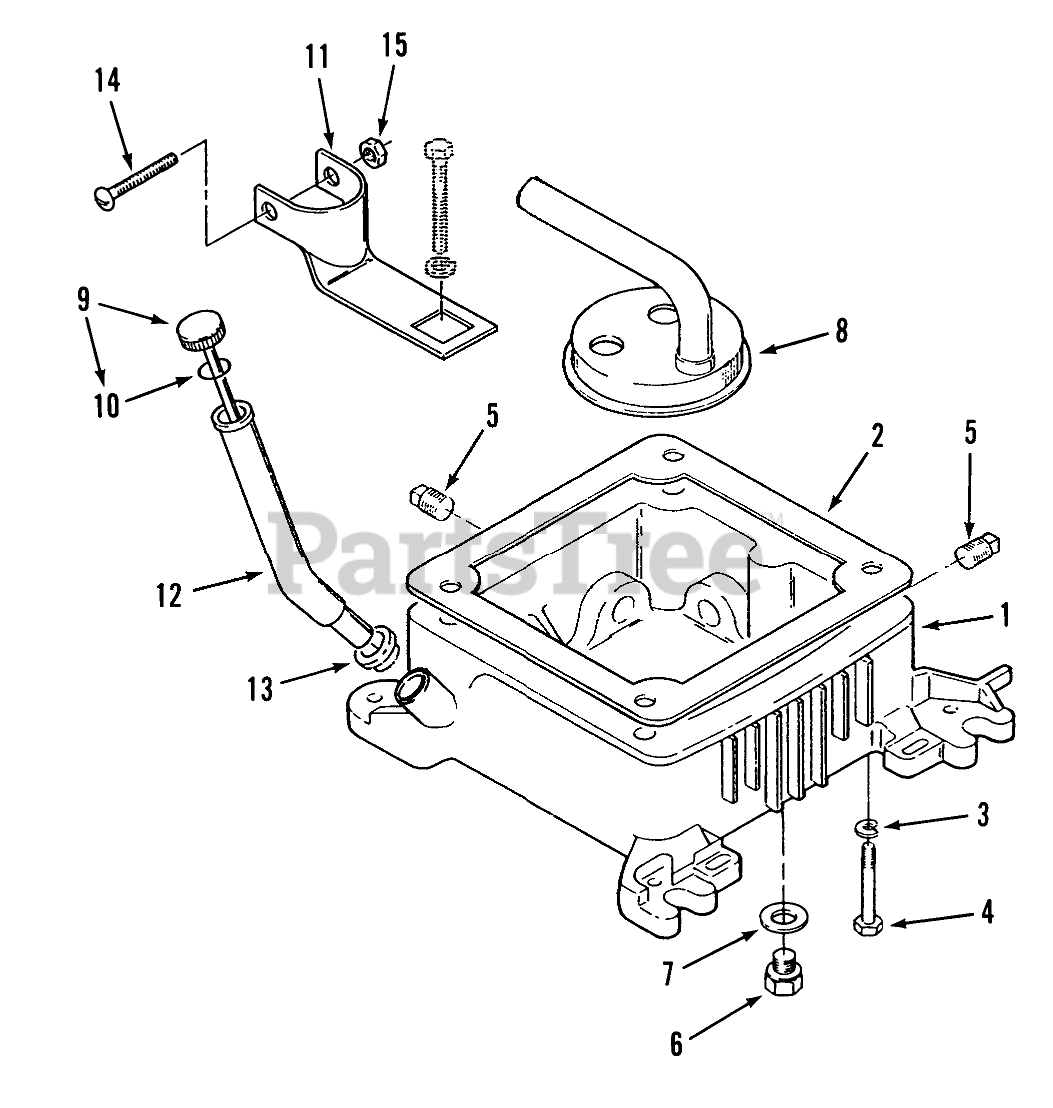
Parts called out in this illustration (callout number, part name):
1	Oil Base (includes all plugs and Plug Gasket)
2	Gasket
3	Lockwasher 3/8
4	HHCS 3/8-16 X 3 3/4
5	Plug
6	Plug
7	Gasket
8	Cup-Oil Pump Intake
9	Oil Fill Cap and Indicator (includes "O" Ring)
10	O-Ring
11	FILL TUBE BRACKET
12	Oil Fill Tube-Chrome 15-3/4" Lg
13	Seal
14	Screw
15	Nut
